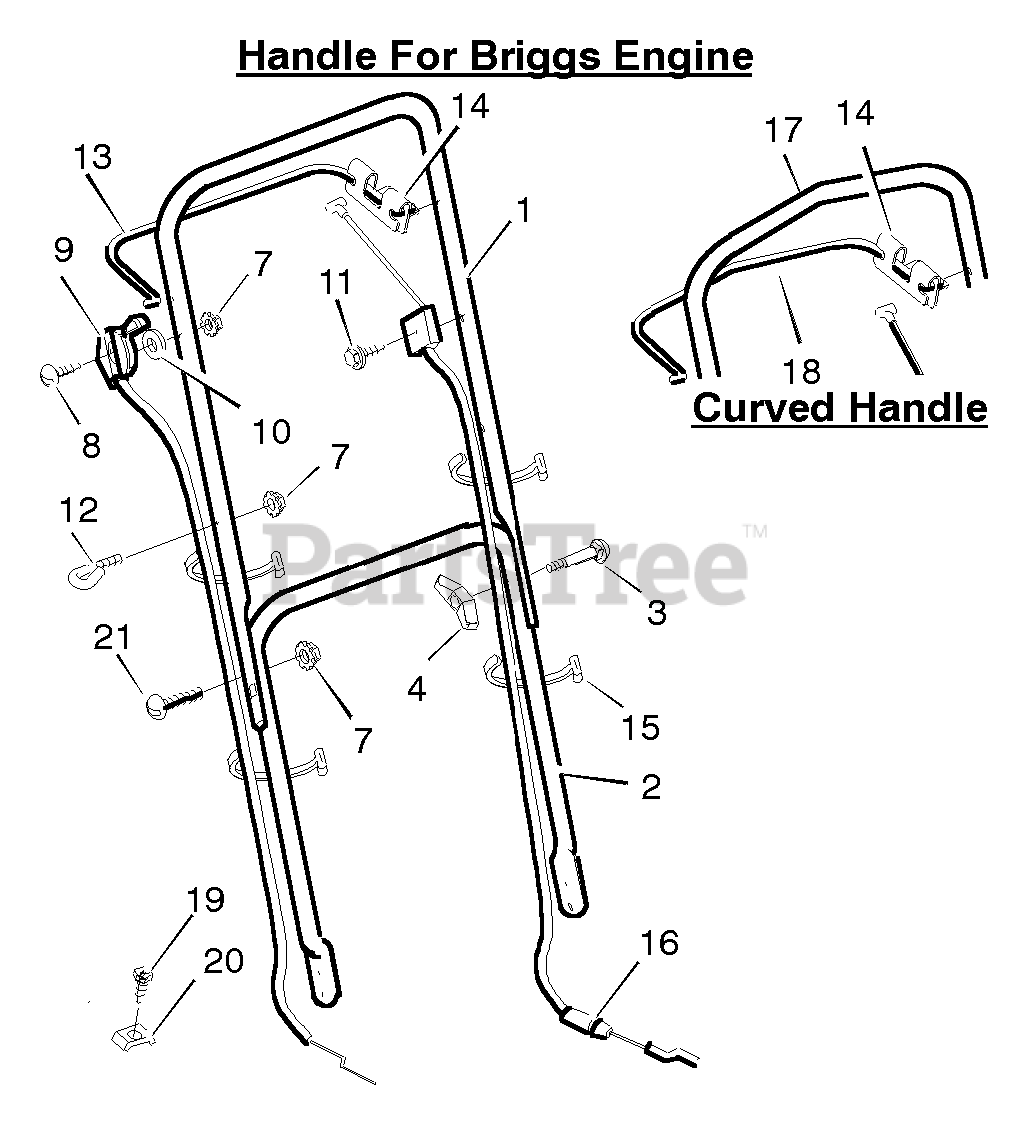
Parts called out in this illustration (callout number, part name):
1	Handle, Upper-Straight (Black)
2	Handle, Lower (Black)
4	Knob, Plastic
7	Locknut
9	Throttle Control
12	GUIDE, ROPE
13	Engine Stop Lever-Straight
14	Bracket, Stop Lever
15	Fastener, Cable
16	Engine Stop Cable
17	Handle, Upper- Curved (Black)
18	Engine Stop Lever-Curved
